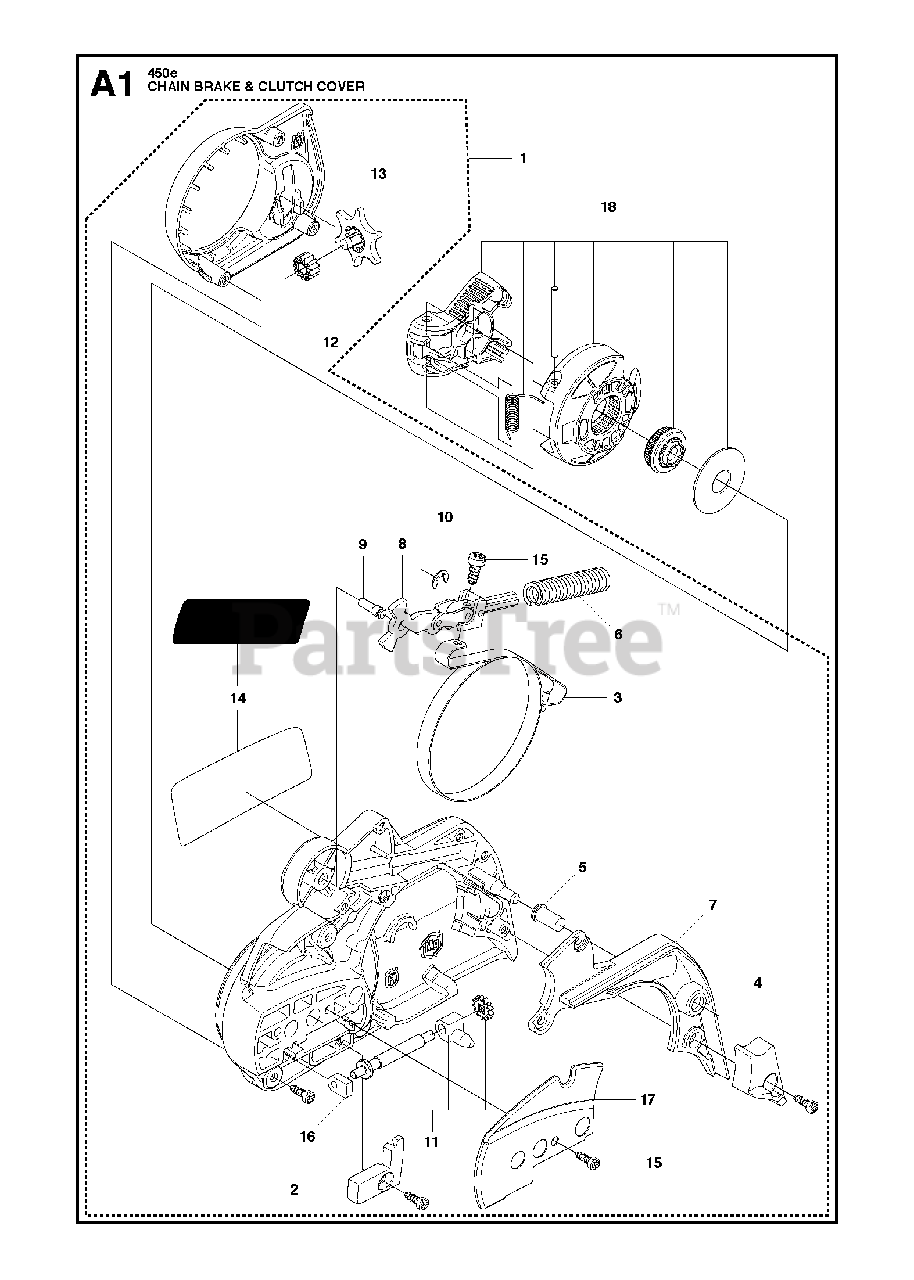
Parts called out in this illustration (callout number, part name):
1	CLUTCH HOUSING COMPLETE
2	COVER
3	BRAKE BAND
4	WEAR GUARD, CHAIN
5	SLEEVE
6	SPRING
7	COVER, CHAIN BRAKE
8	JOINT
9	PIN
10	E-RING 4
11	CHAIN TENSIONER SCREW, COMP.
12	CHAIN TENSIONER WHEEL, COMP.
13	HEAT SHIELD
14	DECAL, CLUTCH HOUSING
15	SCREW
16	BEARING SLEEVE
17	PLATE
18	KNOB, COMPLETE
